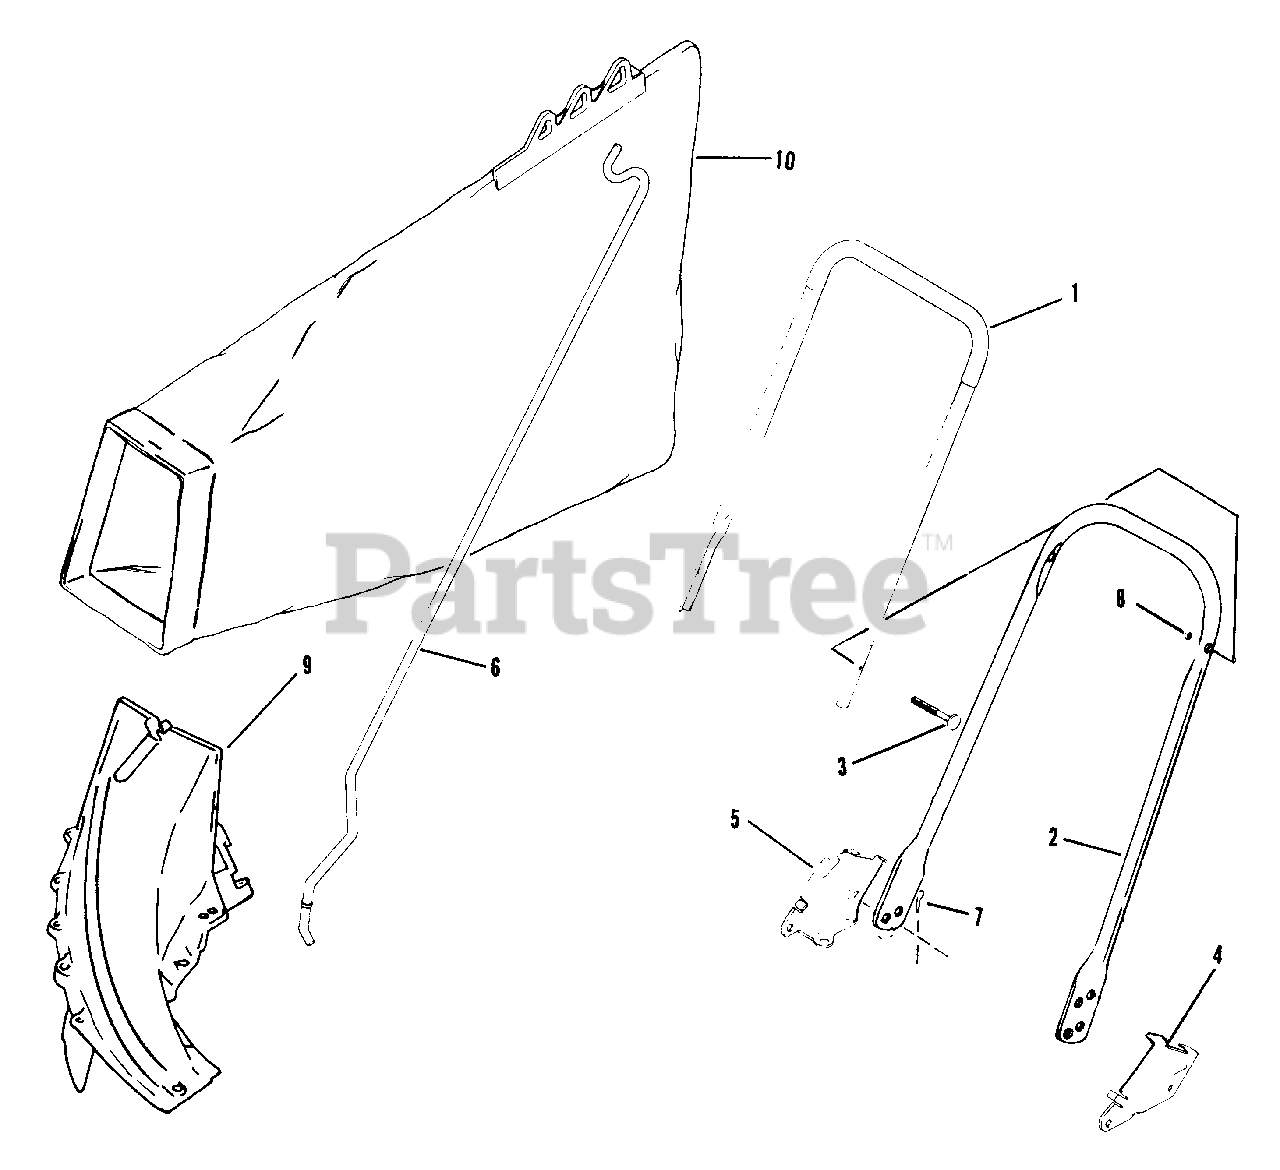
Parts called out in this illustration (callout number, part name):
1	Top Handle & Grip Assembly
2	Handle Section-Bottom
3	Screw
4	Handle Bracket-L.H.
5	Handle Bracket-R.H.
6	Rod-Grass Bag
7	Hair Pin
8	Nut
9	Chute Assembly
10	Bag Assembly
